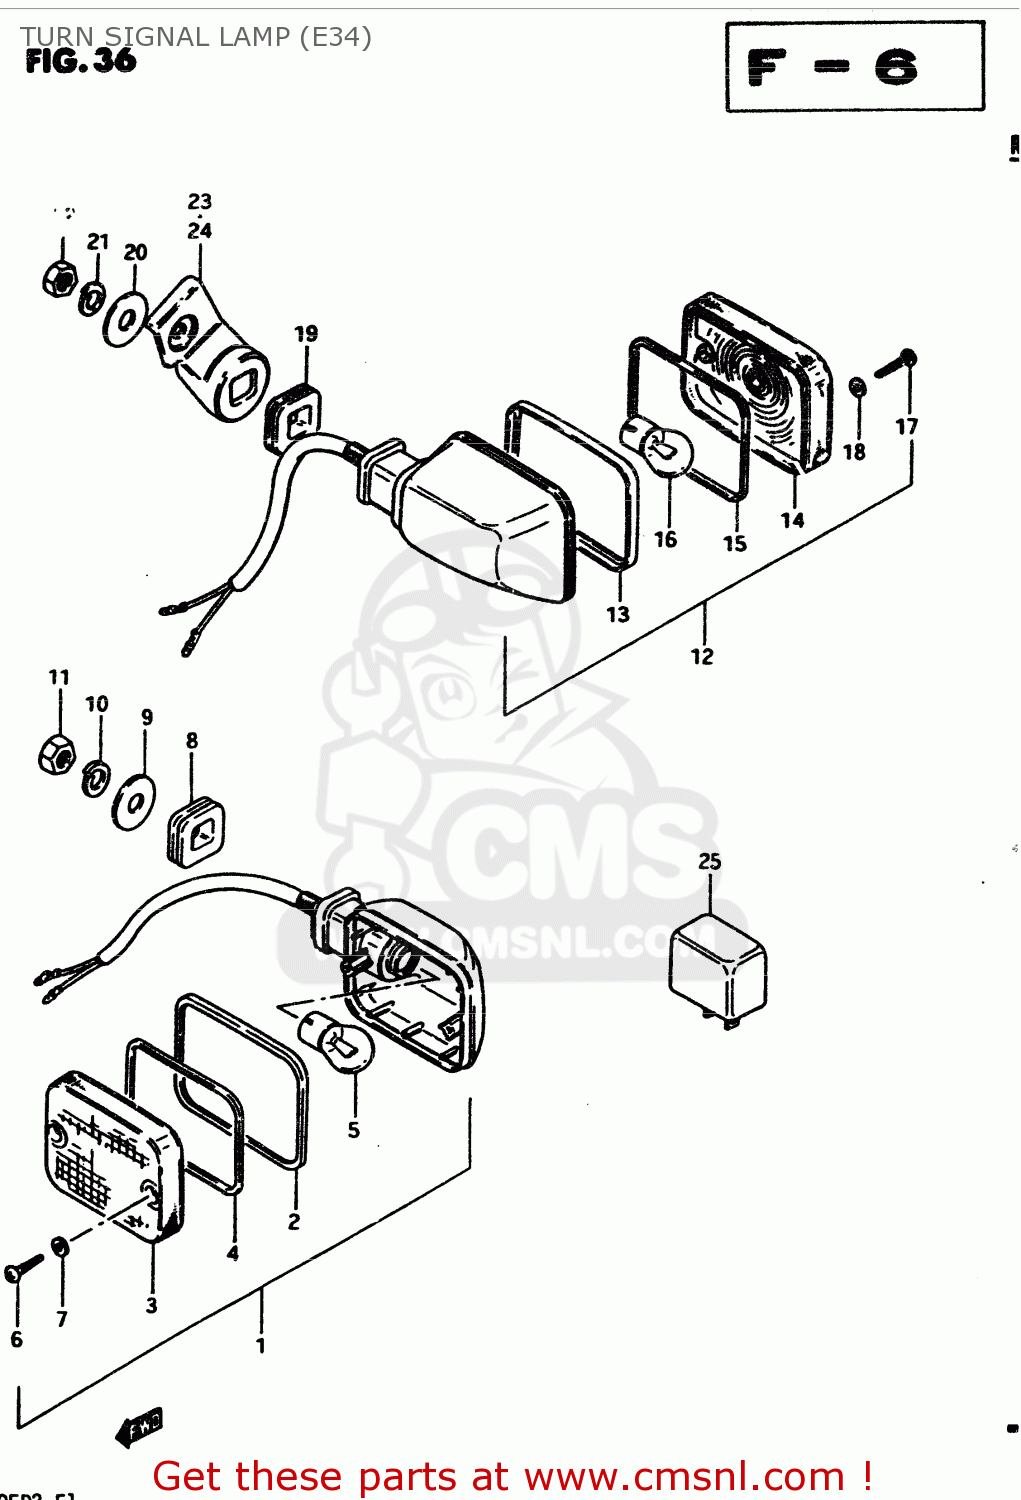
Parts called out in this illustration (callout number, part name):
1	LAMP ASSY,FR T
2	RIM
3	LENS
4	GASKET (NAS)
5	BULB(12V21W)
6	SCREW
7	GASKET (NAS)
8	CUSHION
9	WASHER (10.5X30X2.3)
10	LOCK WASHER
11	NUT
12	LAMP, REAR TURN SIGNAL
13	RIM
14	LENS
15	GASKET (NAS)
16	BULB(12V21W)
17	SCREW
18	GASKET (NAS)
19	CUSHION
20	WASHER (10.5X30X2.3)
21	LOCK WASHER
22	NUT
23	BRACKET,REAR TURN SIGNAL
24	BRACKET,REAR TURN SIGNAL
25	RELAY,TURN SIGNAL
